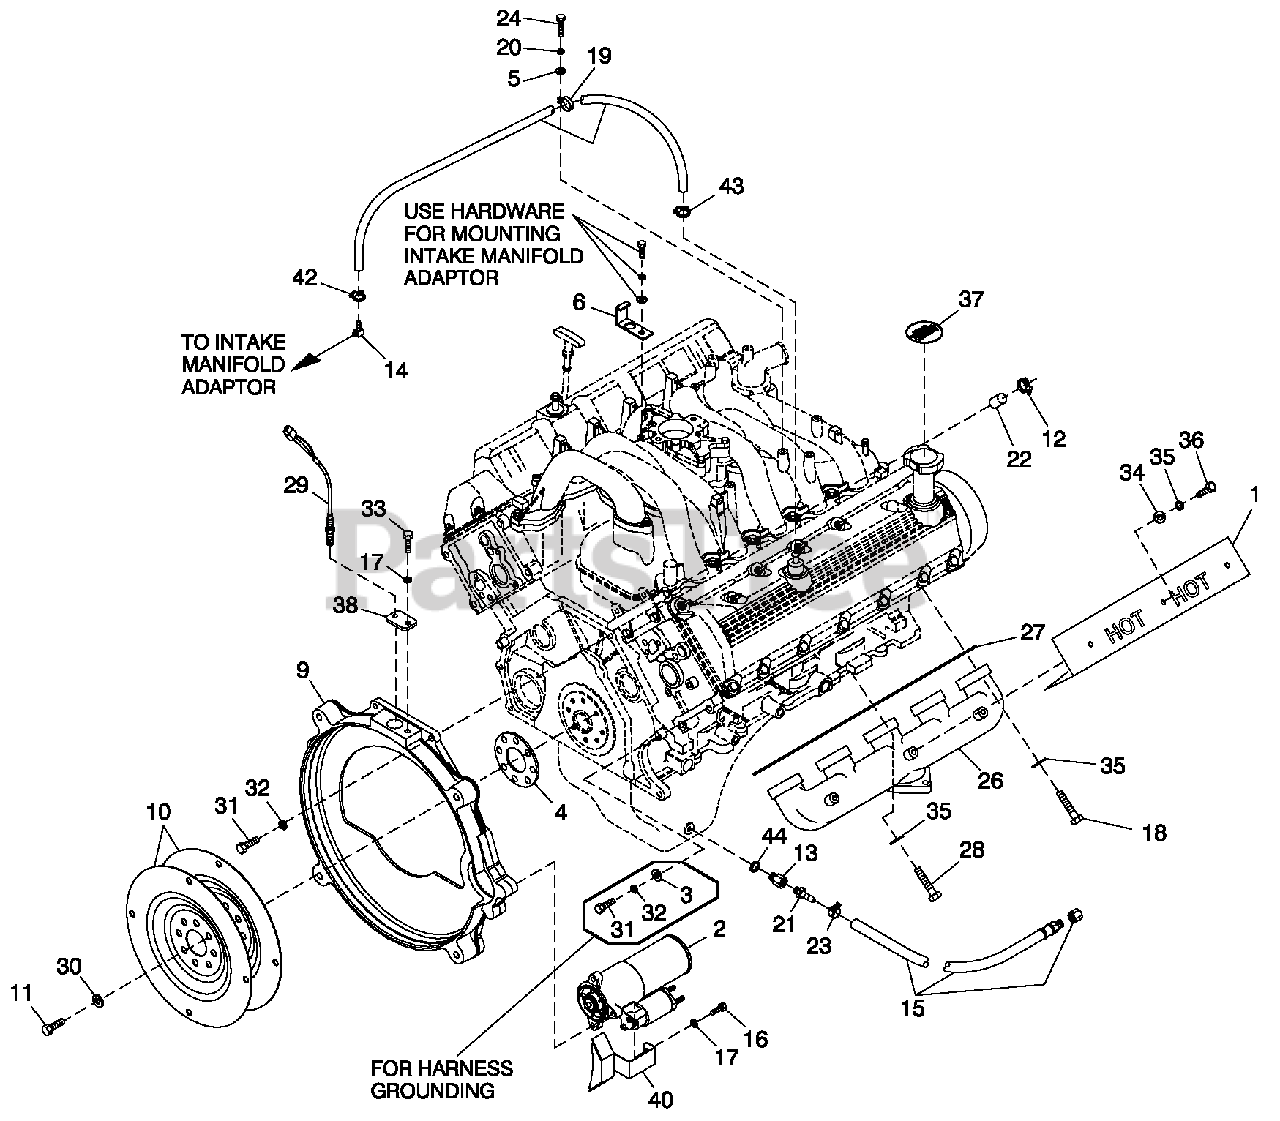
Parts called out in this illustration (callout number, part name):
1	HEAT SHIELD EXHAUST
2	STARTER MOTOR FORD V-10 ENGINE
3	WASHER FLAT 3/8-M10 ZINC
4	SPACER FLEXPLATE 5.4L/6.8L (1800 RPM UNITS ONLY)
5	WASHER FLAT 1/4-M6 ZINC
6	BRACKET SIGNAL CONDITIONER
8	WASHER NYLON .565
9	ENGINE ADA PTER 5.4L/6.8L
10	FLEX PLATE 2 POLE (1800 RPM UNITS ONLY)
11	SCREW HHC M10-1.0 X 25 G10.9
12	CLAM P HOSE #10 .56 - 1.06 (1800 RPM UNITS ONLY)
13	ADAPTER M14-1.50X 3/8 N PT
14	BARBED STR 1/4 N PTX5/8
15	HOSE DRAIN ASSY 28"
16	SCREW HHC M8-1.25X 30 G8.8
17	WASHER LOCK M8-5/16
18	SCREW SHC M8-1.25X35 SS
19	CLAM P VINYL .75X.343Z
20	WASHER LOCK M6-1/4
21	BARBED STR 3/8 N PTX3/8
22	CAP HOSE (1800 RPM UNITS ONLY)
23	HOSE CLAM P BAND 5/8"
24	SCREW HHC M6-1.0X 16 G8.8
25	HOSE COOL 5/8" ID 250#W P (14")
26	EXH MANIFOLD MACH 6.8L V-10
27	GASKET EXHAUST MANIFOLD
28	SCREW HHC M8-1.25 X 35 SS G8.8
29	ASSY MAG PICKUP (3/8-24 MALE)
30	WASHER FLAT .43X1.00
31	SCREW SHC M10-1.5 X 25 G12.9
32	WASHER LOCK M10
33	SCREW HHC M8-1.25X 20 G8.8
34	WASHER FLAT M8 SS
35	WASHER LOCK M8 SSTL
36	SCREW HHC 5/16-18 X 1/2 SSTL
37	DECAL REFER TO OWNERS MANUAL
38	PLATE MAG PICK-U P ADAPTOR
40	COVER STARTER 5.4 & 6.8 FORD CPL
43	CLAM P HOSE #10 .56-1.06
44	ELBOW 90D 1/4 N PT F-M BRASS
